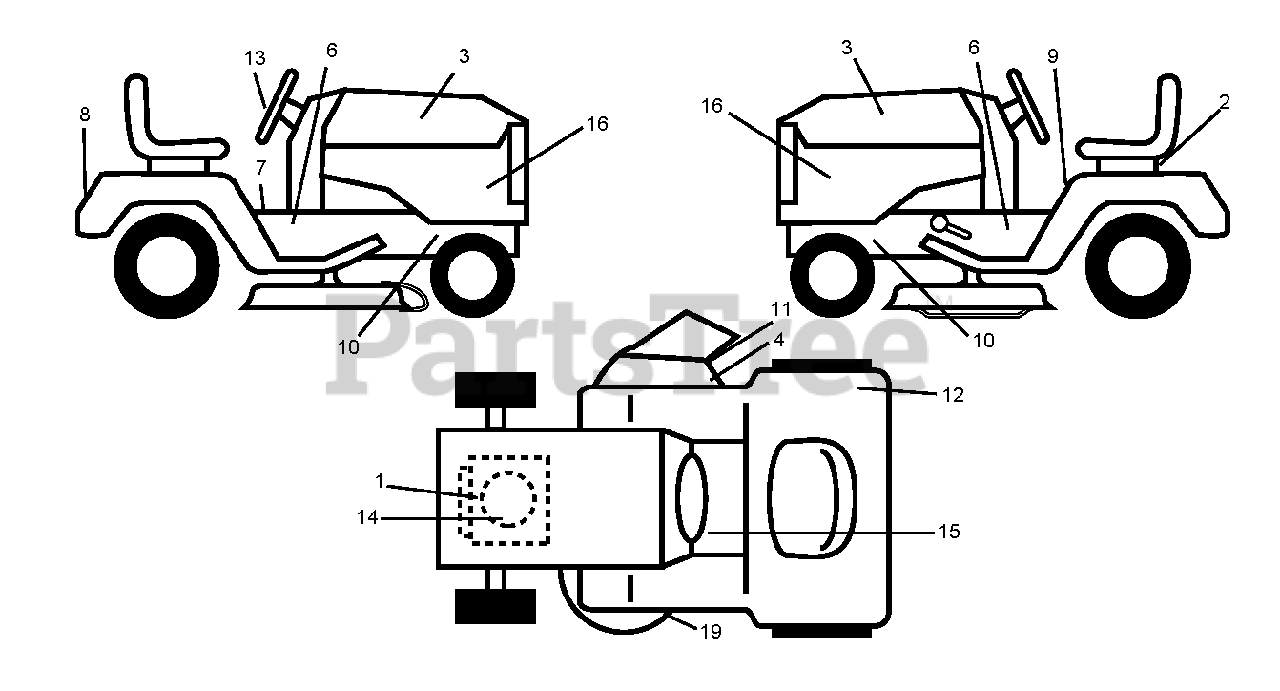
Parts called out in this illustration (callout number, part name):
2	DECAL BTRY SYMBOLS
4	DECAL, DEFLECT WARNING
6	DECAL.CHAS.TURBO
7	DECAL PARK BRAKE
11	DECAL.INTERNATIONL.CUTFINGER
12	Decal, 100 DB/CE
19	DECAL.V-BELT.SCHEMATIC.36/38/9
